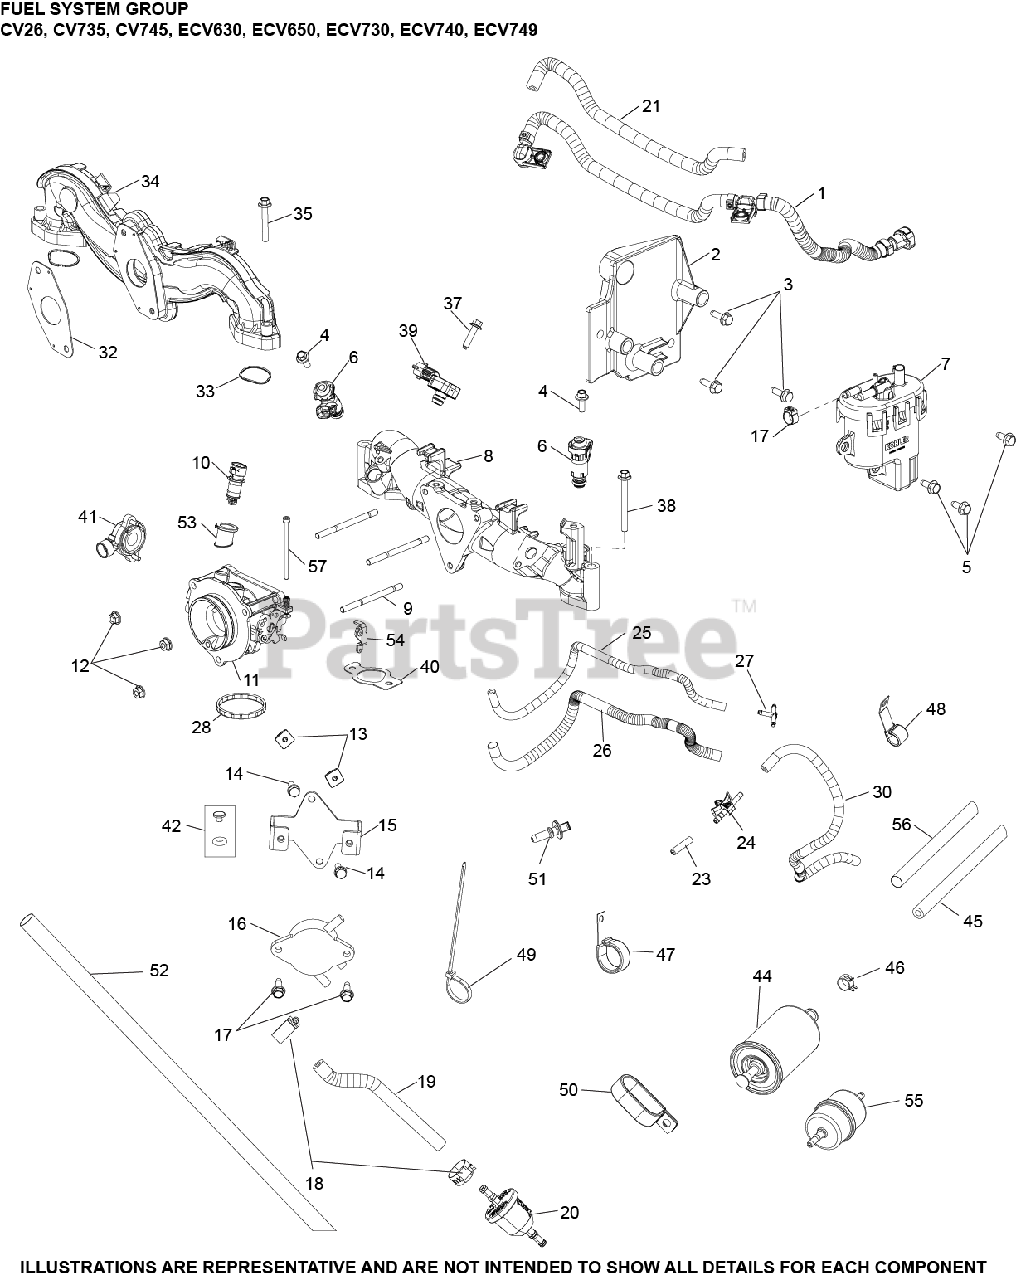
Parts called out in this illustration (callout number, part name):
1	FUEL HOSE ASSY (STRAIGHT FITTING)
2	KIT,BAFFLE, FUEL MODULE
3	SCREW, THREAD FORMING
4	SCREW, FLG M6X1.0X16
5	SCREW, FLG M6X1.0X16
6	INJECTOR, FUEL
7	KIT, FUEL PUMP MODULE USE 25 393 16-S
8	KIT, MANIFOLD
9	STUD,M6X1.0X84
10	SENSOR, AIR TEMPERATURE
11	BODY, THROTTLE ASSEMBLY INCLUDES THROTTLE POSITION SENSOR
12	NUT, FLG M6X1.0
13	NUT, PLASTIC - BLACK
14	SCREW, TAP M6X1.7X18
15	BRACKET, FUEL PUMP MOUNTING
16	PUMP, FUEL
17	SCREW, THREAD FORMING
18	CLAMP, HOSE (KM)-USE 25 237 31-S
18	CLAMP, HOSE
19	HOSE,LW PERM.FUEL 24.00"-USE 25 111 81-S
21	SLEEVE, FUEL LINE
22	CLAMP, OETIKER
23	CAP, MASKING
24	CONNECTOR, EVAPORATIVE
26	SLEEVE, ANTI-ABRASION
27	CONNECTOR, TEE - USE 25 155 56-S
28	O-RING, THROTTLE BODY
30	HOSE, EVAPORATIVE (15.0)
37	SCREW, FLG M6X1.0X25
39	SENSOR, MAP
40	GASKET, INTAKE MANIFOLD USE 24 041 79-S
41	SENSOR, THROTTLE POSITION
42	KIT, FUEL INJECTOR O-RING
50	CLAMP, INSULATED DOUBLE
55	FILTER, FUEL
